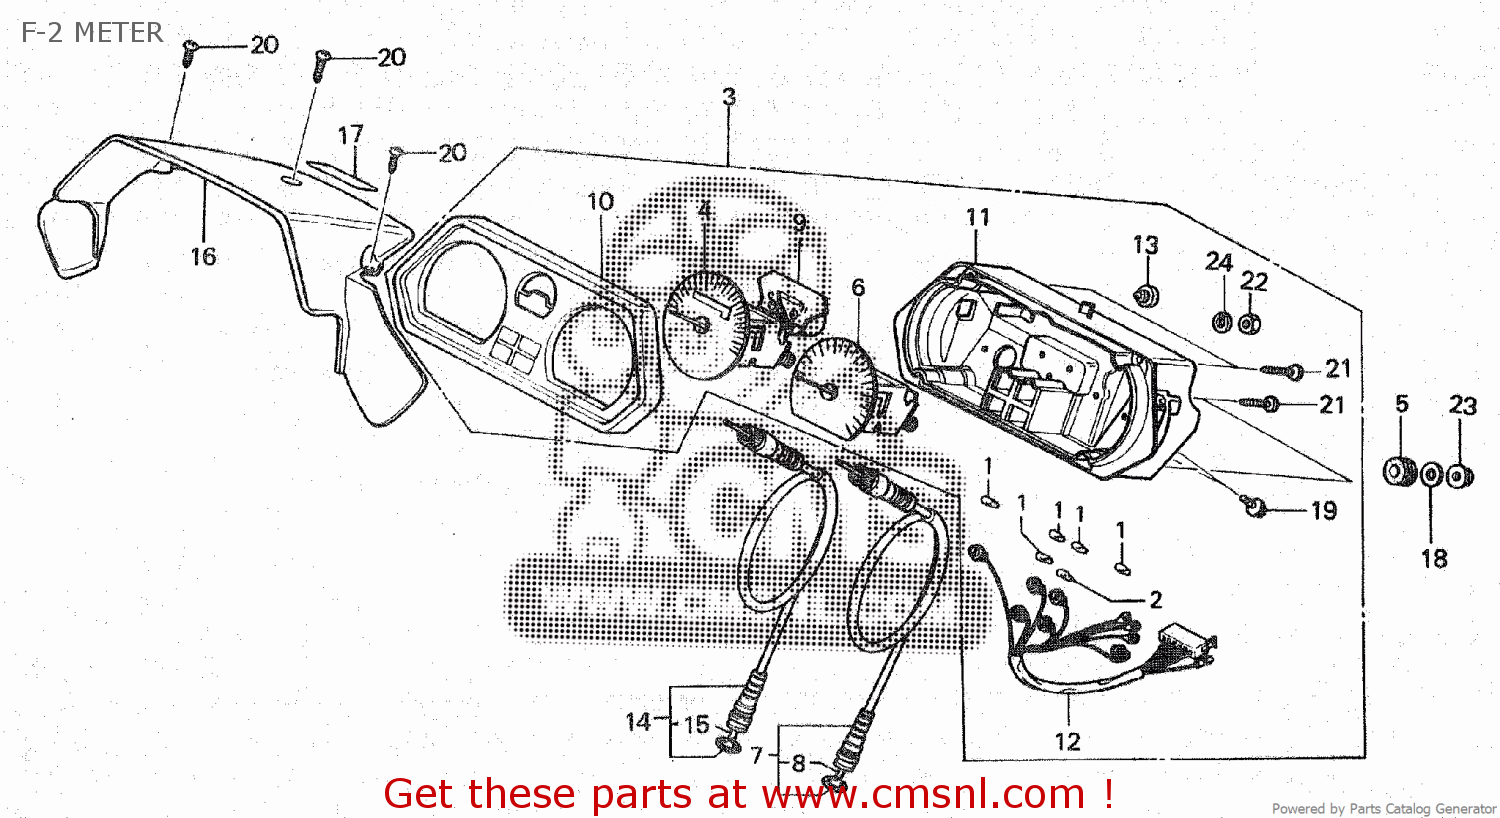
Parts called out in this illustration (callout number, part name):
1	BULB,WEDGE BASE
2	BULB,WEDGE BASE
3	METER COMB
4	SPEEDOMETER ASSY
5	RUB,SPEDMT.MTG.
6	TACHOMETER ASSY
7	CABLE,TACHOMETER
8	CABLE,INNER
9	METER ASSY., TEMPERATURE
10	CASE,METER UPPER
11	CASE,METER LWR.
12	SOCKET COMP.
13	PLUG,CHAIN CASE
14	CABLE,SPEDMT.
15	CABLE,INNER
16	VISOR,METER
17	EMB,METER VISOR
18	WASHER, SPECIAL, 6MM
19	SCREW,PAN 4X8
20	TAPPING,5X12
21	SCREW,TAP.,4X16
22	NUT HEX 3MM
23	NUT HEX CAP,6MM
24	WASHER,SPG.,3MM
